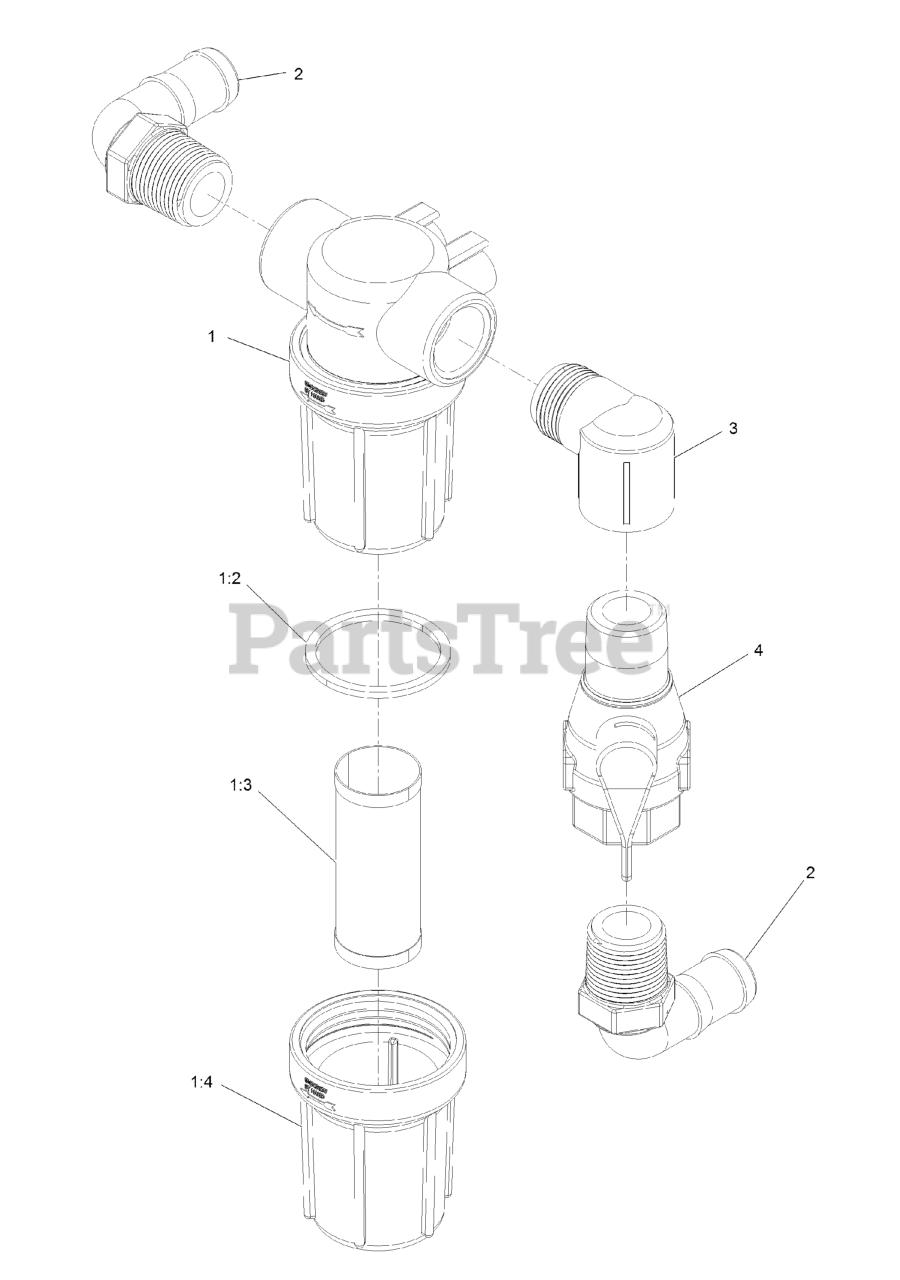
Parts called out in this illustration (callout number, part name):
1	STRAINER-LINE
1:2	GASKET-HEAD, LINE STRAINE
1:3	SCREEN-STRAINER, 30 MESH
1:4	BOWL-STRAINER
2	ELBOW-HOSEBARB
4	VALVE-BALL
